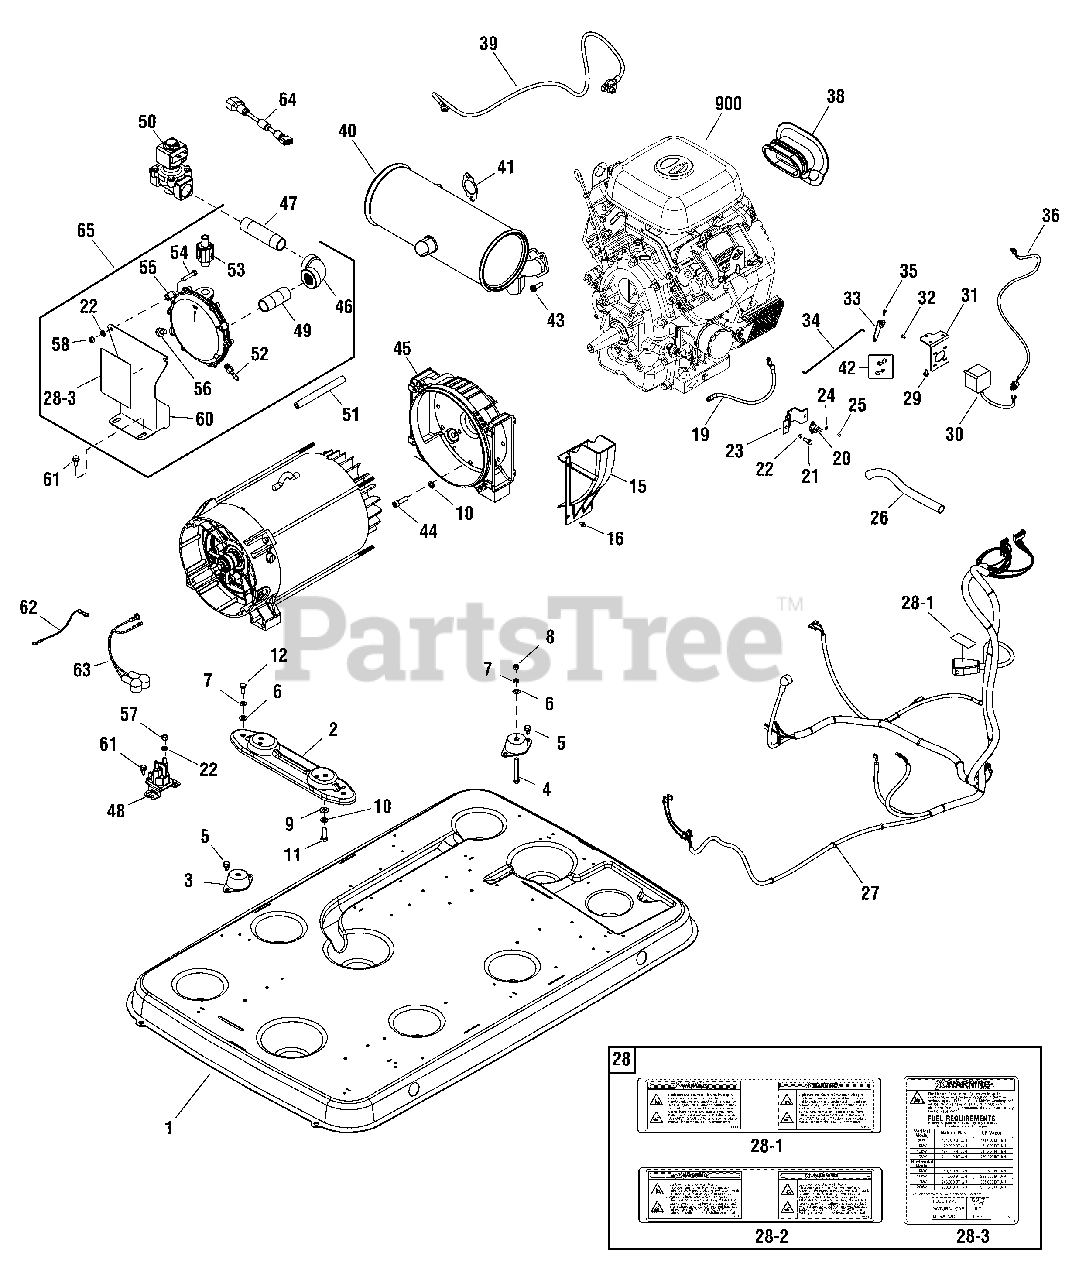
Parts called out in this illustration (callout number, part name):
3	MOUNT, Vibration
4	* CAPSCREW, Hex Head, 5/16-18 x 2-1/2
6	* WASHER, Flat, M8
7	* WASHER, Lock, M8
8	* NUT, 5/16-18
9	* WASHER, Flat, M10
10	* WASHER, Lock, 3/8
11	* CAPSCREW, Hex Head, 3/8-16 x 1
12	* CAPSCREW, Hex Head, 5/16-18 x 3/4
16	* SCREW, M5-0.8 x 10
21	CAPSCREW, Hex Head, M6-1.0 x 16
22	* WASHER, Lock, 1/4
24	* WASHER, Shakeproof, #4
25	SCREW
27	HARNESS, Wiring
28	DECAL SHEET, Warnings
28-1	DECAL, Warning Explosion
28-2	DECAL, Warning Explosion
28-3	DECAL, Fuel Requirements
30	STEPPER MOTOR
31	BRACKET
32	* CAPSCREW, Hex Head, M3-0.5 x 6
33	ARM, Link
35	* CAPSCREW, Hex Head, M3-0.5 x 8
36	HARNESS, Wiring
39	WIRE, Battery, Ground
43	* SCREW, M8 x 25
45	ADAPTER, Engine
48	SOLENOID, Starter
53	VALVE, LP/NG Switch
54	* CAPSCREW, Hex Head, M6-1.0 x 30
55	REGULATOR
57	* NUT, 1/4-20
58	* NUT, Hex, M6-1
60	BRACKET
61	BOLT
62	WIRE, Ground Relay
65	FUEL REGULATOR ASSEMBLY
900	** ENGINE
